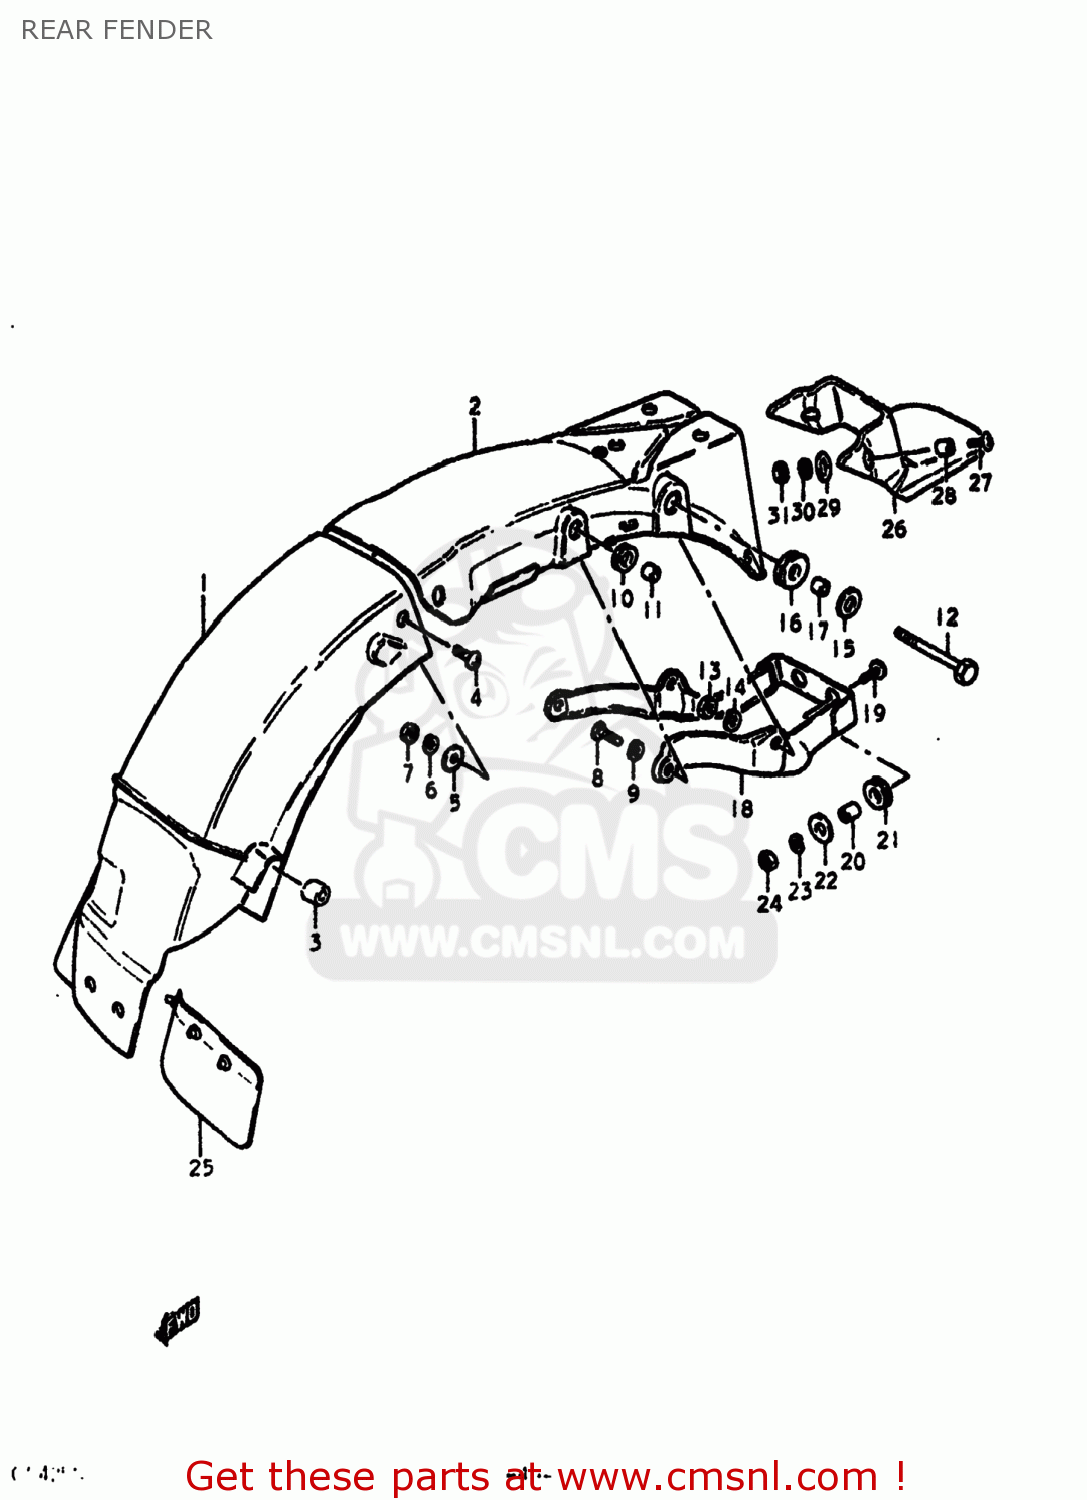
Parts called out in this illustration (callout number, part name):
1	FENDER,REAR
2	BODY,RR FENDER RR
3	CUSHION
4	SCREW
5	WASHER (5.5X16X1.2)
6	LOCK WASHER
7	NUT
8	BOLT
9	LOCK WASHER
10	CUSHION
11	SPACER(6.1X9X7.5)
12	BOLT
13	NUT
14	LOCK WASHER
15	WASHER(8.5X26X1.2)
16	CUSHION
17	SPACER (8.2X12X7.5)
18	REINFORCEMENT,REAR FENDER
19	SCREW
20	SPACER (6.1X9X9)
21	CUSHION
22	WASHER(6,5X22X1.6)
23	LOCK WASHER
24	NUT
25	MUD GUARD,REAR FENDER
26	EXTENSION,REAR FENDER
27	SCREW (6X15)
28	SPACER(6.2X8.3X5.7)
29	WASHER(6.5X18X1)
30	LOCK WASHER
31	NUT
